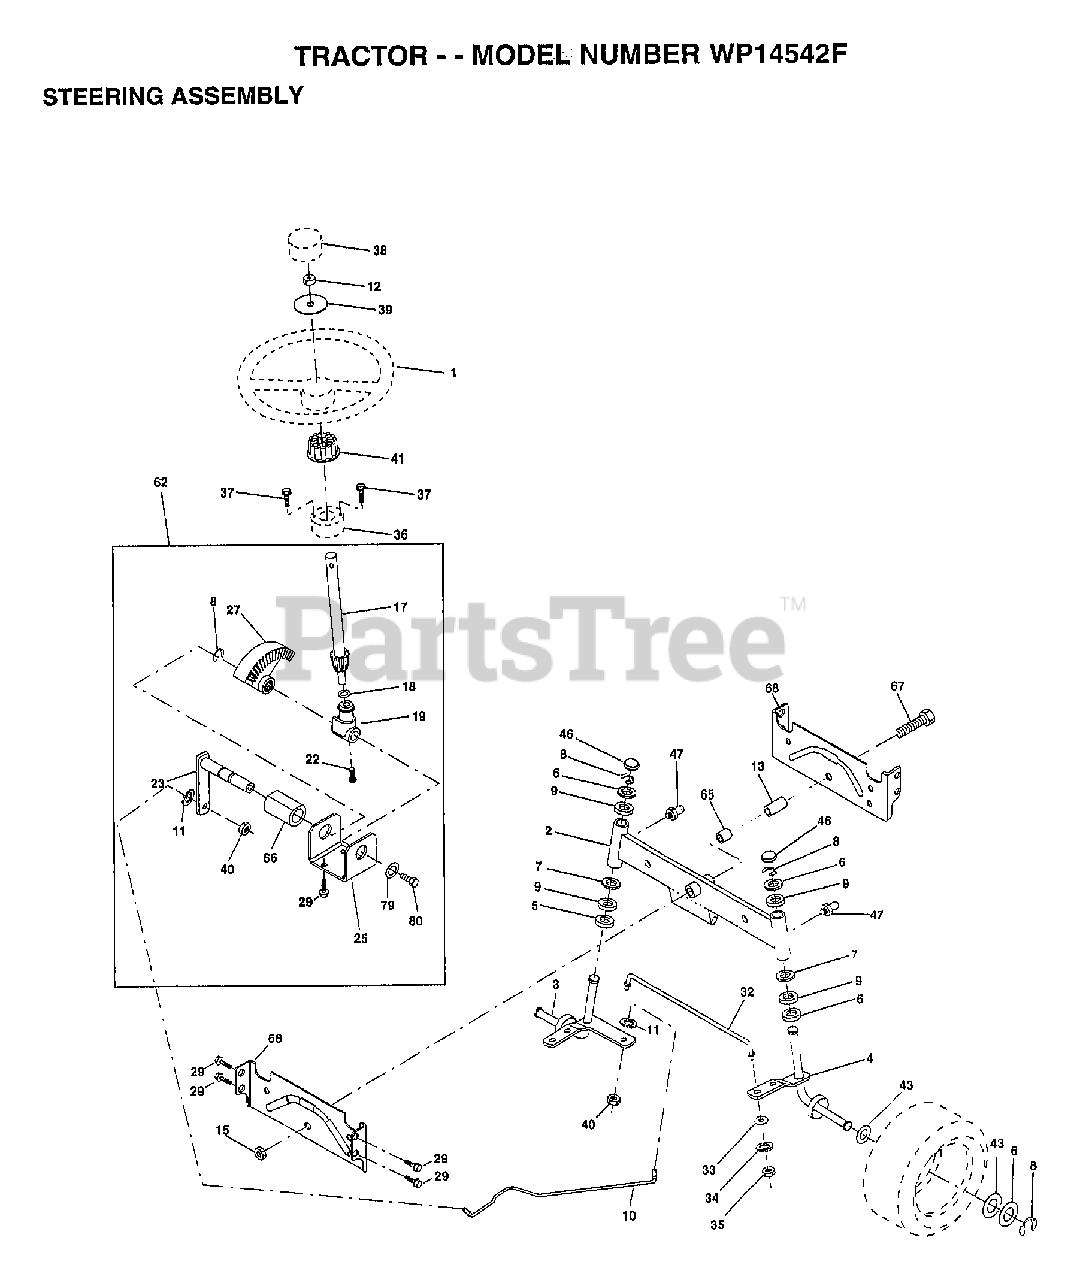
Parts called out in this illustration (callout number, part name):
2	AXLE ASM
3	SPINDLE.ASM.LH
4	"SPINDLE ASM,RH"
5	WASHER .T
6	WASHER
7	WASHER
8	RING
9	COL. SRTG. BEAR.
10	DRAGLINK-STAMPED
11	LOCKWASHER
13	BEARING AXLE
15	"NUT-LOC,FLANGE LT"
17	SHAFT ASM STEERNG
18	THRUST WASHER
19	SUPPORT.SHAFT.STEER
22	SCREW.HX.WSH.HD
23	SHAFT.ASM.PITMAN
25	BRKT-STEERING
27	GEAR SECTOR
29	SCREW
32	ROD.TIE.19.75
33	WASHER M
34	LOCKWASHER
35	NUT.LOCK.5/16-24
36	BUSHING.STRG.3/4
37	"SCREW-TT,10-32 FL"
38	"INSERT,STR WHEEL"
39	WASHER
40	GRIPCO NUT
41	ADAPTER LT
43	WASHER
46	CAP
47	ZERK M
62	KIT.STEER.ASM.LT
65	SPACER AXLE
66	"BEARING-ARM,PITMA"
67	BOLT
68	BRACE AXLE
79	WASHER
80	BOLT.HX.NYLON3/8-16X3/
